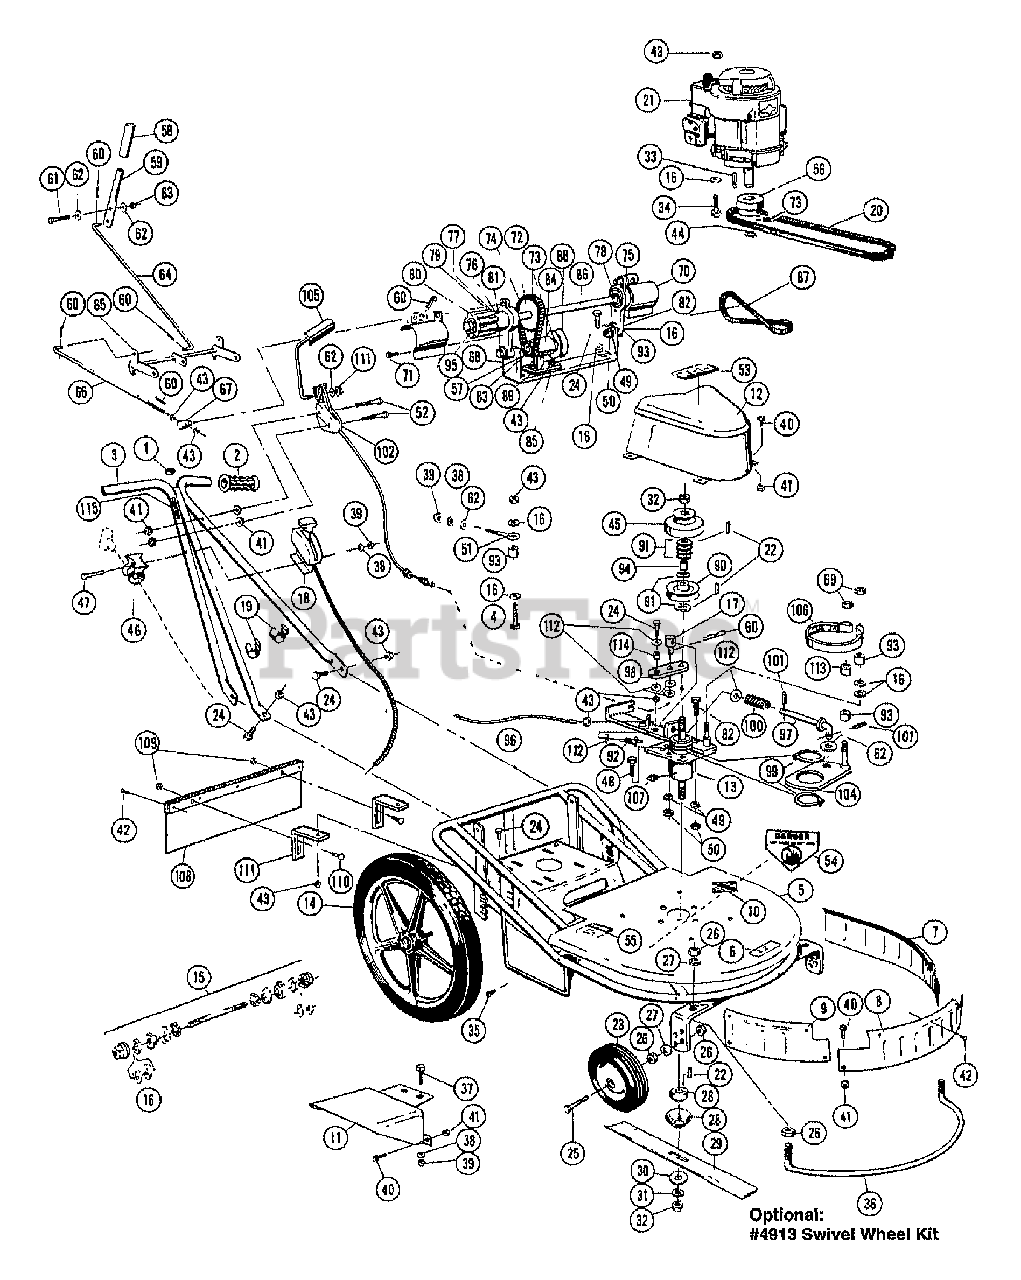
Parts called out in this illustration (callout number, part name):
1	PLUG-HANDLE
2	GRIP-HANDLE
3	ASSM-HANDLEBAR 22"
4	SCREW 5/16-18 x 2-1/4" HHC
6	CUTTING WIDTH DECAL 22
7	GUARD-LEFT 20" & 24"
8	GUARD-FRONT 22"
9	GUARD-RIGHT
10	DECAL-CAUTION
11	DEFLECTOR-DISCHARGE
12	HOOD-MOWER
13	ASSM-SPINDLE 22"
13	HOUSING-SPINDLE 22"
13	SHAFT-SPINDLE 22"
14	ASSM-WHEEL 16" W/KNOBBY
14	ASSM-WHEEL 16" W/O TIRE
14	TIRE-16" KNOBBY
15	KIT-AXLE FOR NYLON WHEEL
15	DUST COVER SET (2)
16	WASHER-FLAT 5/16 SAE
17	PIN-CONNECTING ROD
19	CLIP-THROTTLE CABLE
20	BELT-DRIVE #464-22"
21	ENGINE, BRIGGS 5HP, VERTICAL SHAFT #130902
21	ENGINE, BRIGGS 5HP, IC VERTICAL SHAFT #131922
22	KEY-3/16-1/2
23	WHEEL-FRONT 6"
24	SCR-HH 5/16-18X1.0 G5 ZP
25	SCR-HH 1\2X2.75
26	NUT-HEX JAM 1/2-13
27	WASHER-LK .5
28	KIT-BLADE ADAPTOR
28	BLADE ADAPTOR NUT
28	BEARING GUARD
29	BLADE-22" REPLACE PRO MWR
30	WASHER-FLAT 5/8
31	WASHER-LK .625 ZP
32	NUT-5/8 HEX
33	KEY-1/4 X L
34	SCR-HH 5/16-18X1.5 G5 ZP
35	SCR-#14 X .75
36	BUMPER-22"
37	SCR-HH 1/4-20 X .625
38	WASHER-LK .25 ZP
39	NUT-HEX 1/4-20 ZP
40	SCR-HH #10-24X.375
41	NUT-3/16 HEX LOCK
42	POP RIVET
43	NUT 5/16-18
44	RETAINER 1"
45	ASSM-DRUM/PULLEY
46	GUIDE-ROPE
47	SCR-HH 1/4-20 X 2.25
48	SCR-HH 3/8-16X1.0 G5 ZP
49	WASHER-LOCK 3/8
50	NUT-HEX 3/8-16 ZP
51	BOLT-EYE 1/4 X 3
52	SCR-HH #10-24 X 2.25
53	DECAL-"PRO"
54	DECAL-BLADE WARNING
55	DECAL-DISCHARGE CHUTE
56	CLUTCH-SINGLE 1 BORE
57	SCR-SET (W02350401)
58	GRIP-POWER LEVER
59	LEVER-POWER SP
60	PIN-HITCH (24" MODEL)
61	SCR-HH 1/4-20X1.5 G5ZP
62	WASHER-FLAT 1/4
63	NUT-LK 1/4-20
64	ROD-UPPER 22" SP/24
65	BRKT-FULCRUM 22" SP
66	ROD-LOWER 22" SP
67	CONNECTOR-PIVOT PIN
68	BRKT-LOWER DR 22" SP
69	NUT W/NYLON INSERT 3/8-24
70	GUARD-ROLLER LT
70	GUARD-ROLLER RT
71	SCR #10-24 X .625
72	SPROCKET-36 TOOTH
73	SCR-SET 5/16 X .312
74	CHAIN-43 PITCH SP
75	ASSM-HSG ROCKER SP
75	HOUSING-ROCKER ARM SP
76	PIN-ROLL 3/16X1.25
77	PIN-DOWEL
78	PIN-ROLL 3/16X.812
79	SPRING-DOWEL RETURN
80	ROLLER-SPLINED
81	RATCHET-ROLLER DR LT
81	RATCHET-ROLLER DR RT
82	BOLT-HH 3/8-16X1.5 FTH ZP
83	SPROCKET-10 TOOTH
84	ASSM-HSG JACKSHAFT
84	SPROCKET-10 TOOTH
84	HOUSING-JACKSHAFT
84	JACKSHAFT
85	SCR-FH 5/16-18 X 1
86	SHAFT-ROLLER DR 22" SP
87	BELT-DRIVE #284-24"
89	SHIM-CHAIN ADJUST
90	PULLEY-3 1/2 X 5/8
91	WASHER-5/8 ID X .060
92	SWITCH-ENGINE STOP
93	BUSHING-ROCKER ARM
94	SPACER-5/8 ID X 1/2
95	RING-GRIP
96	GROUND WIRE ASSEMBLY
98	LEVER-BLADE BRAKE-84
99	RING-RETAINER
100	SPRING-BLADE BRAKE
101	PIN-ROLL 1/8 X .75
102	KIT-BBC CABLE
104	ASSM-BRKT BRAKE BAND
105	ASSM-HANDLE BLADE BRAKE
106	BAND-BRAKE 3 3/4
107	GREASE FITTING
108	ASSM-REAR GUARD
109	NUT-H/LK 5/16-18 NYLOCK
110	BOLT-CARRIAGE 5/16-18X1"
111	BRKT-MOUNTING 24"
112	WASHER - 5/16 SAE
113	SPACER-3/8 ID X 1/2
114	BUSHING-BRAKE LEVER-84
115	DECAL-WHEEL DRIVE
